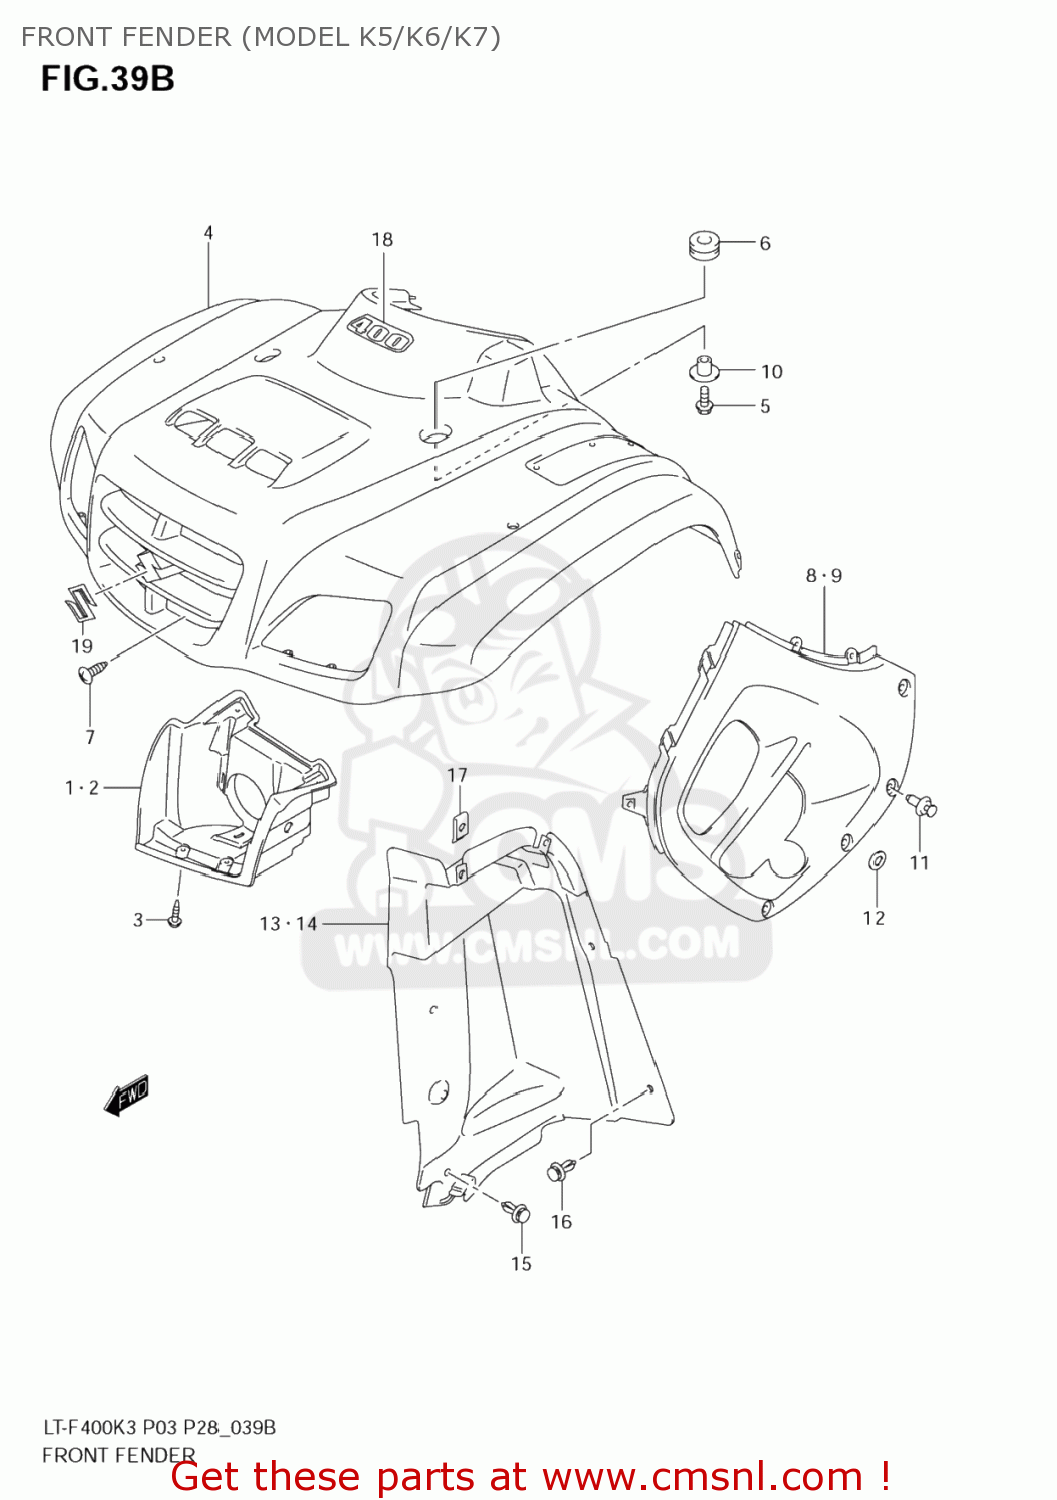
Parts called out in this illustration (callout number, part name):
1	HUIS.KOPLAMP
2	HOUSING,HEADLA
3	SCREW
4	FENDER,FR
5	BOLT
6	CUSHION
7	SCREW(6X16)
8	COVER,FR FENDER SIDE,R(BLACK)
9	COVER,FR FENDER SIDE,L
10	WASHER
11	CLIP
12	WASHER
13	MUDFLAP,FENDER INNER,R
14	MUD FLAP,FENDE
15	CLIP
16	CLIP
17	NUT
18	EMBLEM,FR FENDER FR
19	EMBLEM,S
